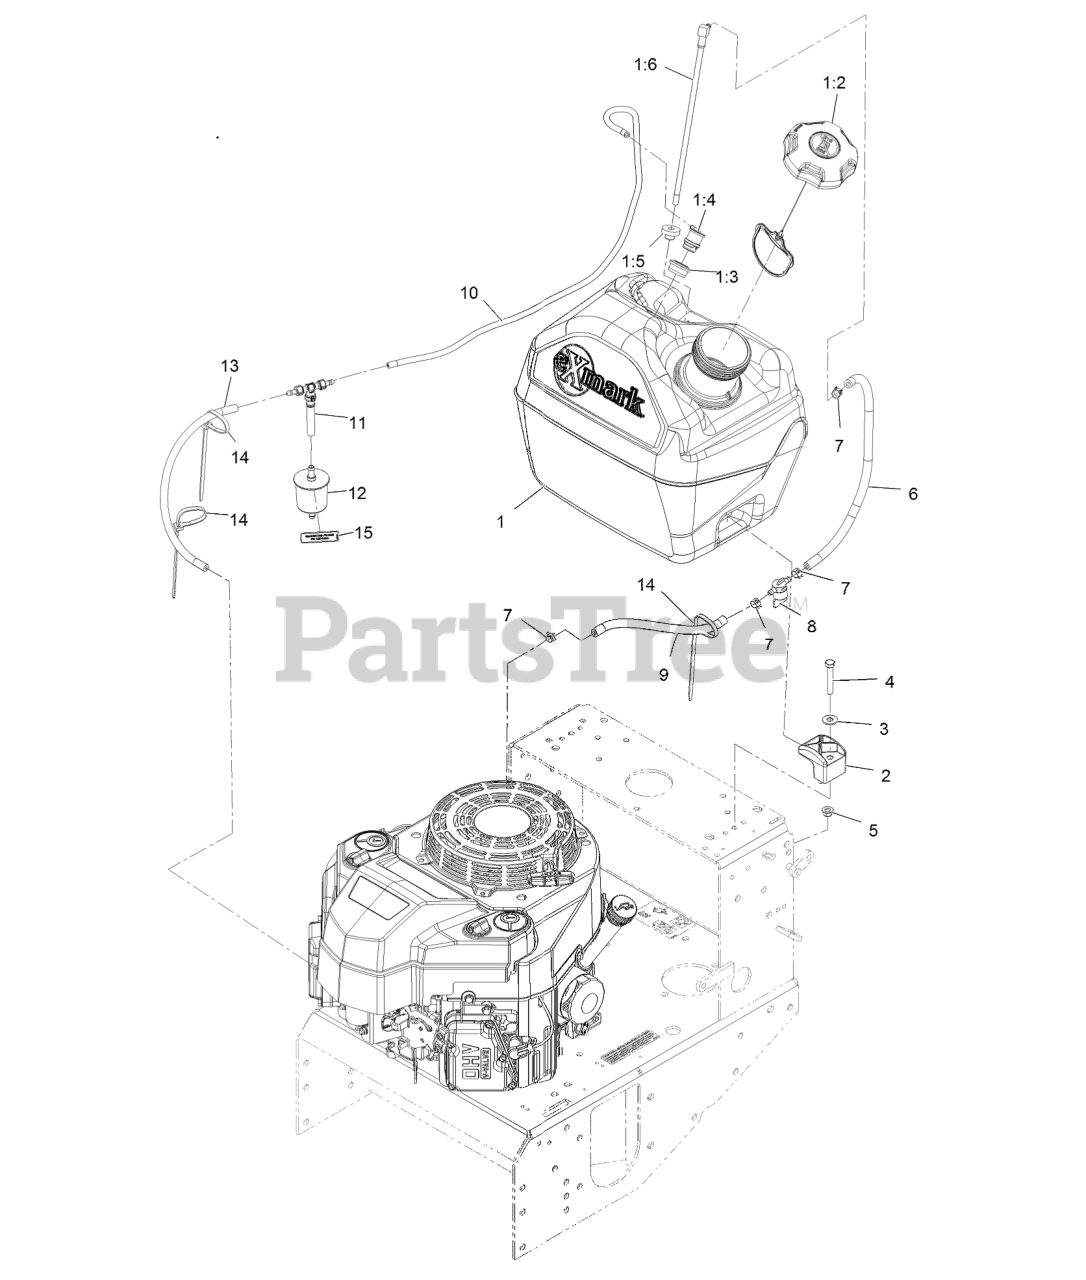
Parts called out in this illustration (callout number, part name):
1	ASM, FUEL TANK
1:3	GROMMET
1:4	VALVE-VENT, FUEL
1:5	FITTING-FUEL, BULKHEAD
3	WASHER-FLAT
4	SCREW-HH
5	NUT-HF, NI
6	HOSE-FUEL
7	CLAMP-HOSE
8	VALVE-FUEL
9	HOSE-FUEL
10	HOSE-EMISSIONS
11	TEE AND CHECK
12	FILTER-FUEL
13	HOSE-FUEL
14	TIE-PLASTIC
15	DECAL-FILTER, EMISSIONS
